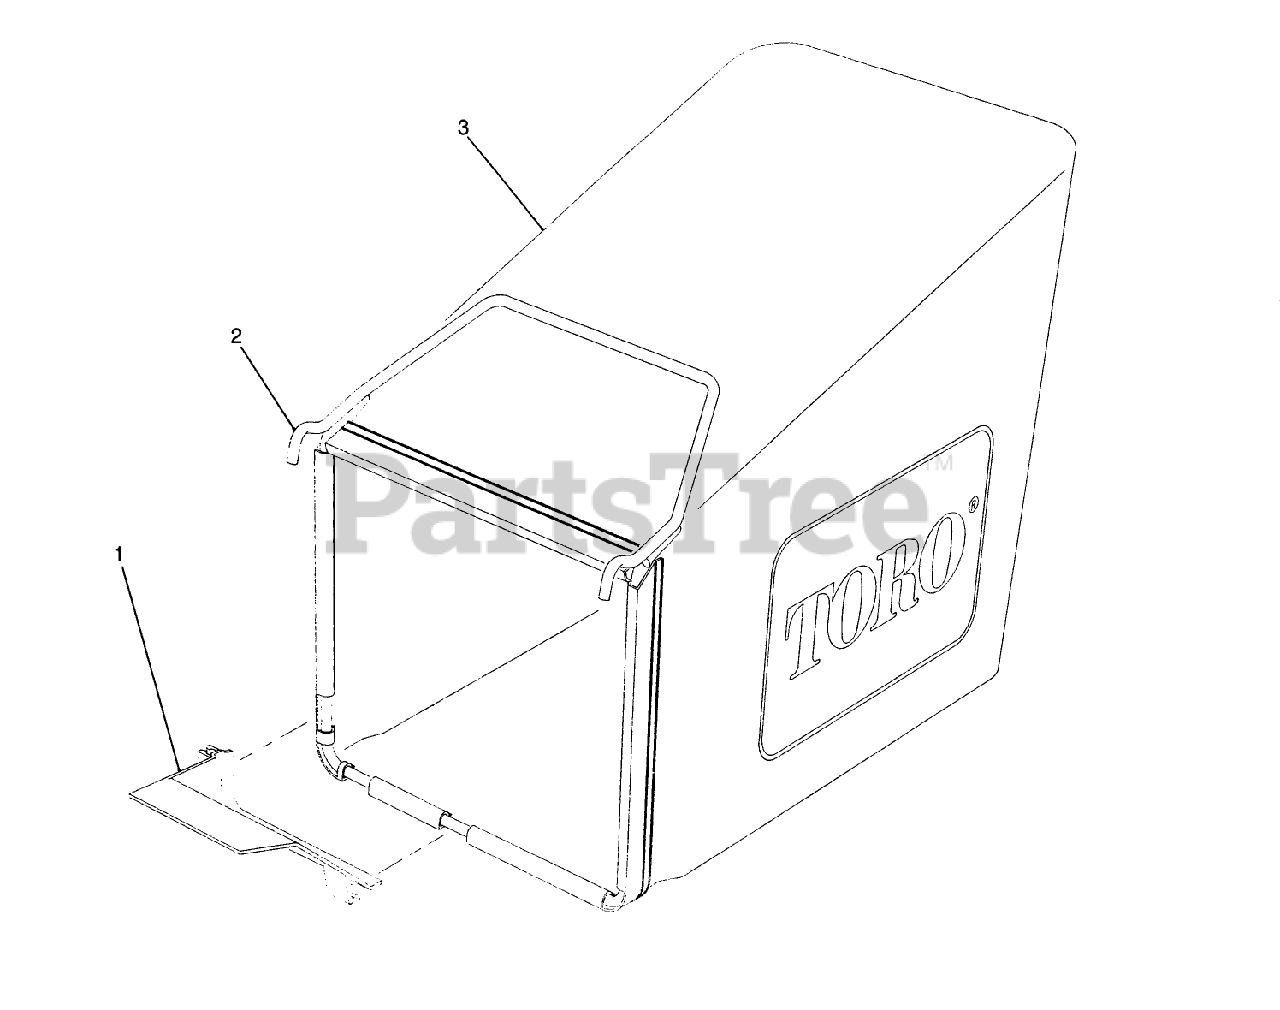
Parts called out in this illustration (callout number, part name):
1	BAG RAMP
2	Frame
3	GRASS BAG ASSEMBLY
